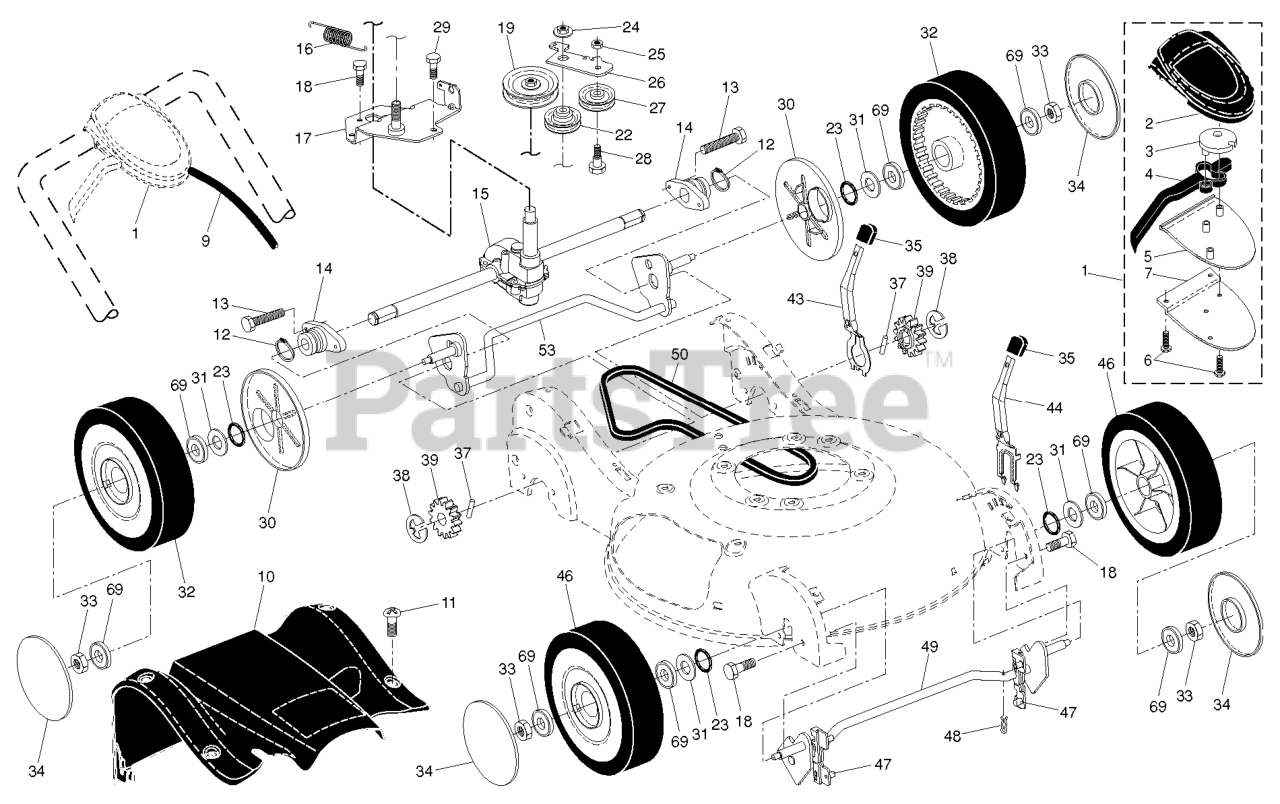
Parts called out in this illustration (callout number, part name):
1	CONTROL.DR.HV.RWGD.GRY/BLU
2	COVER TOP AUTO WALK CONTROL
3	PULLEY.CAM.DRIVE.CONTROL.HV
4	LEVER
5	COVER BOTTOM AUTO WLK CONTROL
6	SCREW, PHILLIPS HEAD 10 X 5/8
7	BRACKET.DRIVE.CONTROL.MOUNT.BL
9	ASM.CABLE.
10	COVER.DRIVE.REAR.21.HV.GRAY
12	RETAINING RING (2 2)(3 2)
13	SCREW.1/4-20X21/4.HEX.
14	BEARING / AXLE SUPPORT
15	TRANSMISSION.21.RWGD.HV
17	BRACKET, GEAR CASE / DRIVE
19	RP PULLEY.DRIVE.EZ
22	PULLEY.IDLER.V-BELT
23	O-RING..070X.487.NEOPRENE
24	NUT.HEX.FLANGE.3/8-16.LOCKNUT
25	NUT.CENTERLOCK.5/16-
26	ARM.IDLER.BZP
27	IDLER PULLEY
28	SHOULDER BOLT
29	SCREW 14-20 X 5/8
30	DUST COVER, WHEEL
31	WASHER.FLAT.1/2
32	WHEEL.9X2.25.LP.TIGER.BLACK
33	NUT.HEX.FLANGE.3/8-16.LO(3 2)
34	HUBCAP.WHEEL.5.SPOKE.SILVER
35	KNOB.SELECTOR.SPRG.H-GRY (2 2)
37	PAWL, DRIVE
38	E-RING 7/16 RE
39	PINION.14.TEETH.FGD
43	LEVER, SELECTOR, HEIGHT, REAR
44	LEVER, SELECTOR, HEIGHT, FRONT
46	WHEEL.9X2.25.LP.TIGER.BLK
47	BUSHING.FRONT.TORQUE.SHAFT
48	SPRING RETAINER
49	SHAFT FRONT
50	BELT, DRIVE
53	SHAFT.ASM.REAR.TORQUE.HV.BZP
69	BEARING.8".WHEEL
